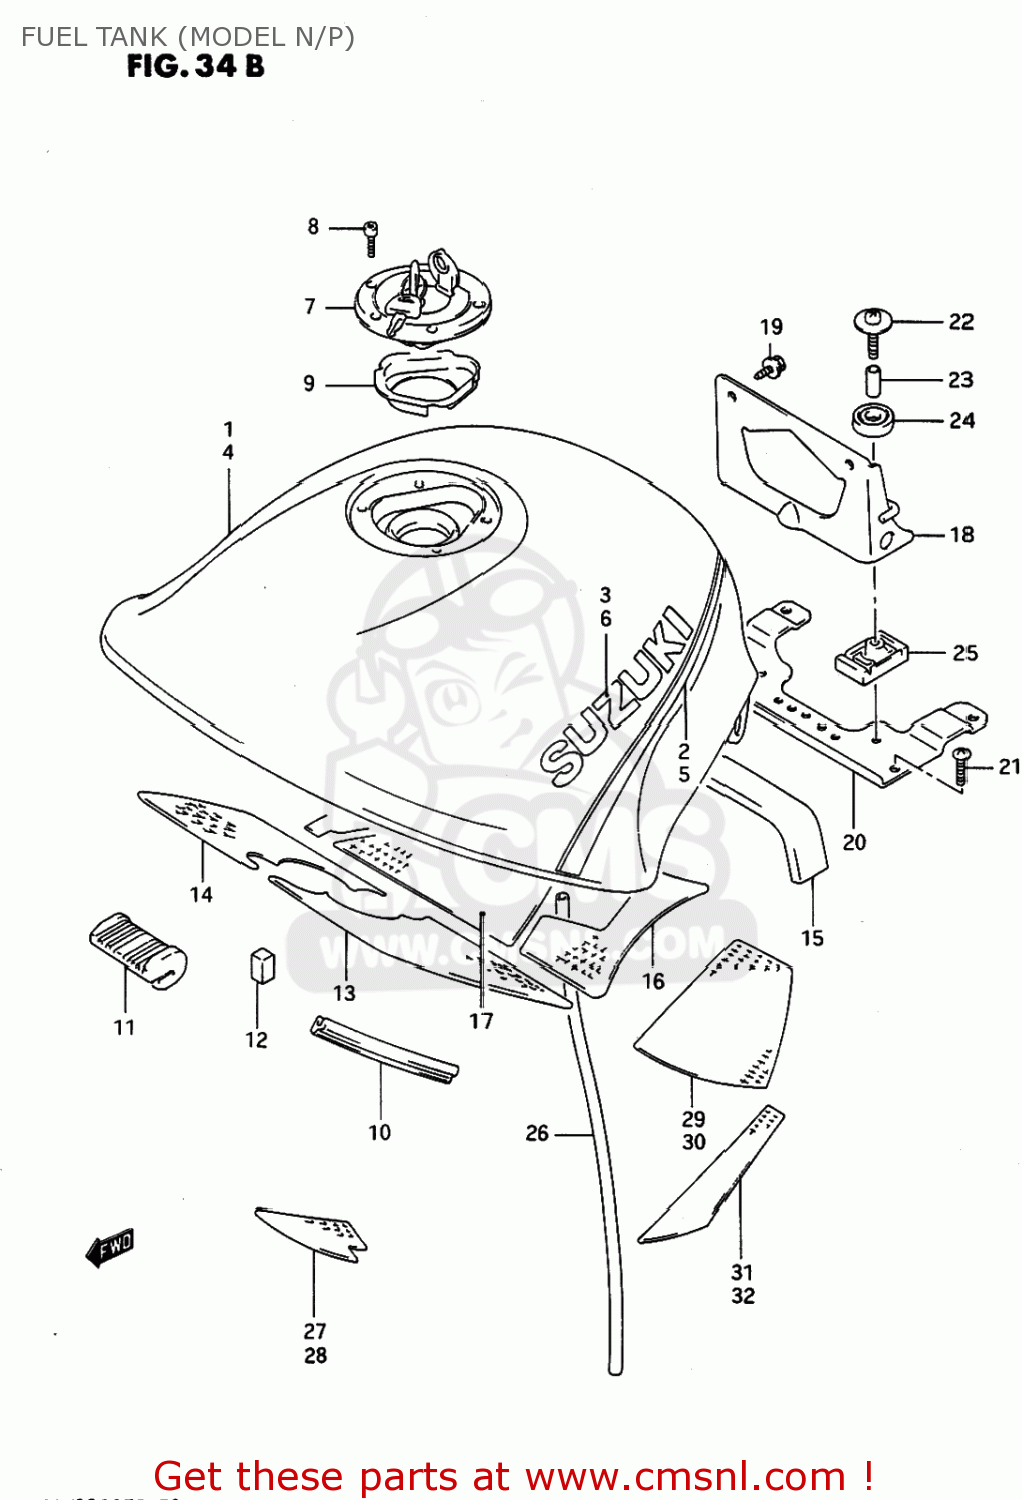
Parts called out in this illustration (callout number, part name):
1	TANK ASSEMBLY,FUEL
2	TAPE,FUEL TANK STRIPE
3	EMBLEM
4	TANK ASSEMBLY,FUEL
5	TAPE,FUEL TANK STRIPE
6	EMBLEM,FUEL TANK
7	CAP SET,FUEL TANK
8	BOLT(5X10)
9	COVER,FUEL TANK INLET
10	MOLDING,FUEL TANK
11	CUSHION,FUEL TANK FR
12	CUSHION,FUEL TANK SIDE
13	HEATSHIELD,FUEL TANK FR,L
14	HEAT SHIELD,FUEL TANK
15	HEAT SHIELD,FUEL TANK
16	HEATSHIELD,FUEL TANK RR,L
17	HEAT SHIELD,FUEL TANK
18	BRACKET COMP,FUEL TANK
19	SCREW(6X16)
20	BRACKET,FUEL TANK RR LOW
21	SCREW, CENTER
22	BOLT L:35,WITH WASHER
23	SPACER (6.4X9X21.5)
24	CUSHION
25	CUSHION
26	HOSE (7X10.2X1000)
27	HEAT SHIELD,FUEL TANK
28	HEAT SHIELD,FUEL TANK
29	HEAT SHIELD,FUEL TANK
30	HEAT SHIELD,FUEL TANK
31	HEAT SHIELD,FUEL TANK
32	HEAT SHIELD,FUEL TANK
